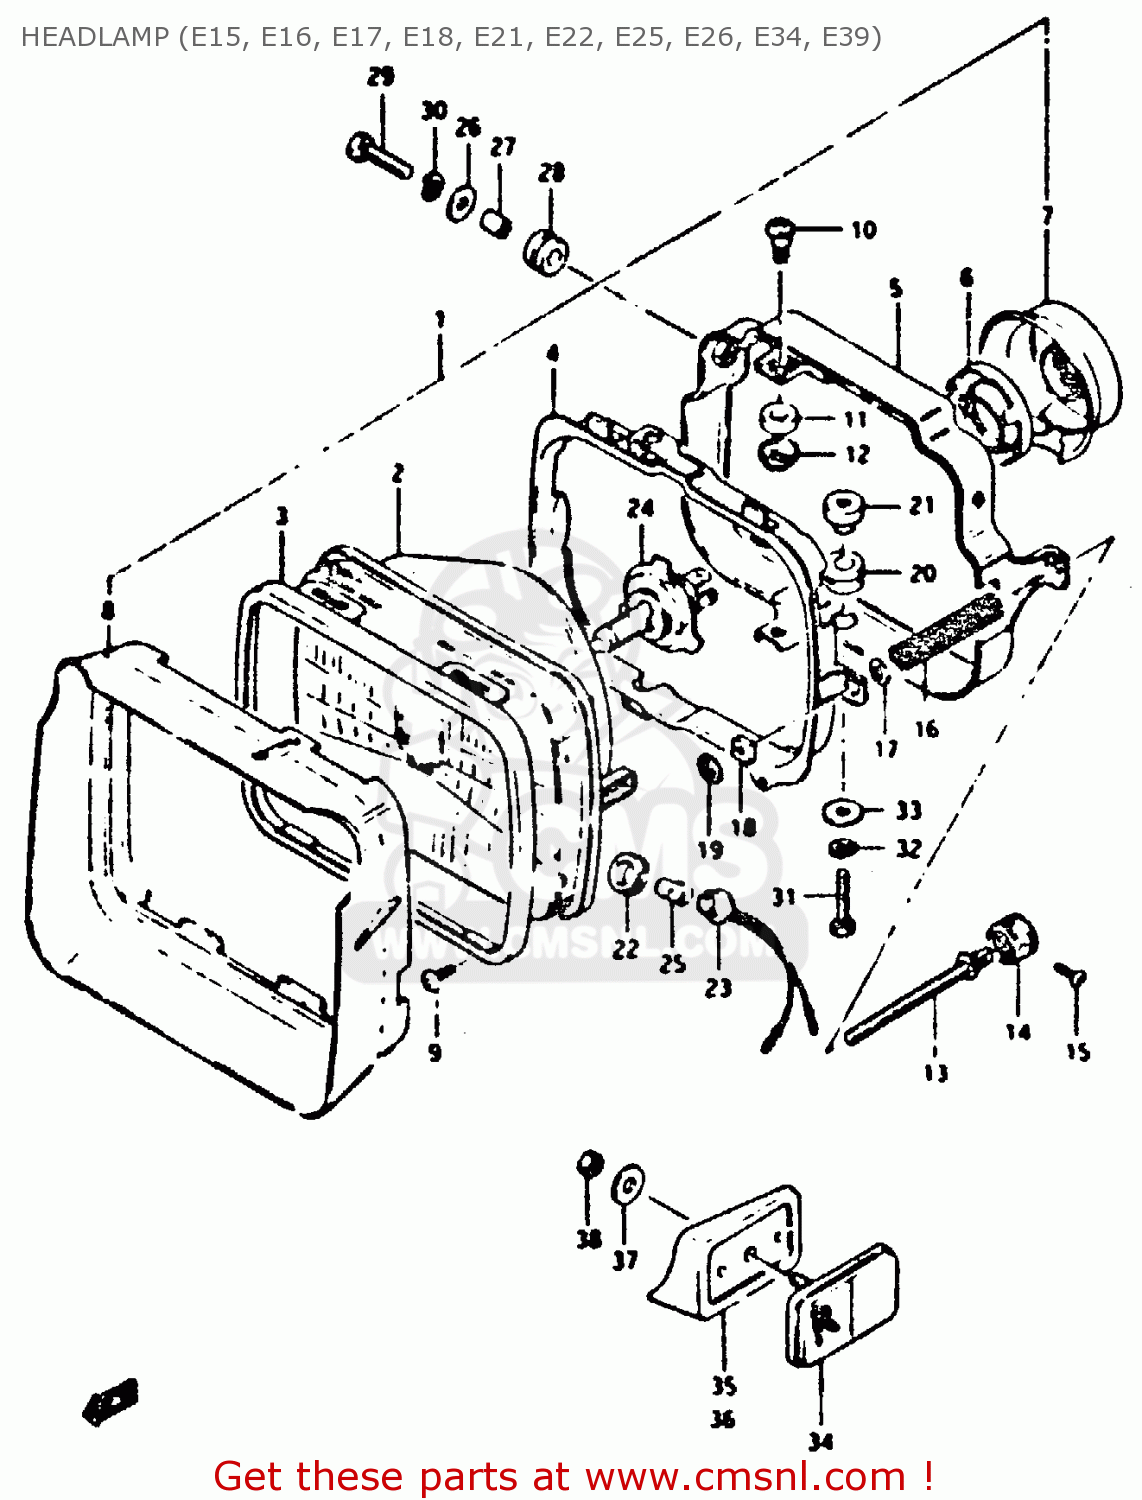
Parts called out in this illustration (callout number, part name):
1	HEADLAMP ASSY
2	LAMP UNIT
3	RETAINER
4	RING,MOUNTING
5	HOUSING
6	HOLDER
7	COVER,HEADLAMP SOCKET
8	SHADE,HEADLAMP UNIT
9	SCREW
10	SCREW
11	SPACER
12	NUT,ADJUSTING
13	SCREW,ADJUSTING
14	KNOB,ADJUSTER
15	SCREW
16	SPRING
17	WASHER
18	NUT
19	NUT,HEADLAMP ADJUSTER
20	CUSHION
21	NUT
22	JOINT,RUBBER
23	SOCKET
24	BULB(12V60/55W,H4)
25	BULB(12V4W)
26	WASHER
27	SPACER (6.1X8X9.5)
28	CUSHION
29	BOLT
30	LOCK WASHER
31	SCREW(6X20)
32	LOCK WASHER
33	WASHER
34	REFLECTOR,REFLEX
35	SPACER,FRONT SIDE REFLECTOR
36	SPACER,FRONT SIDE REFLECTOR
37	WASHER(5.2X16X1)
38	NUT
